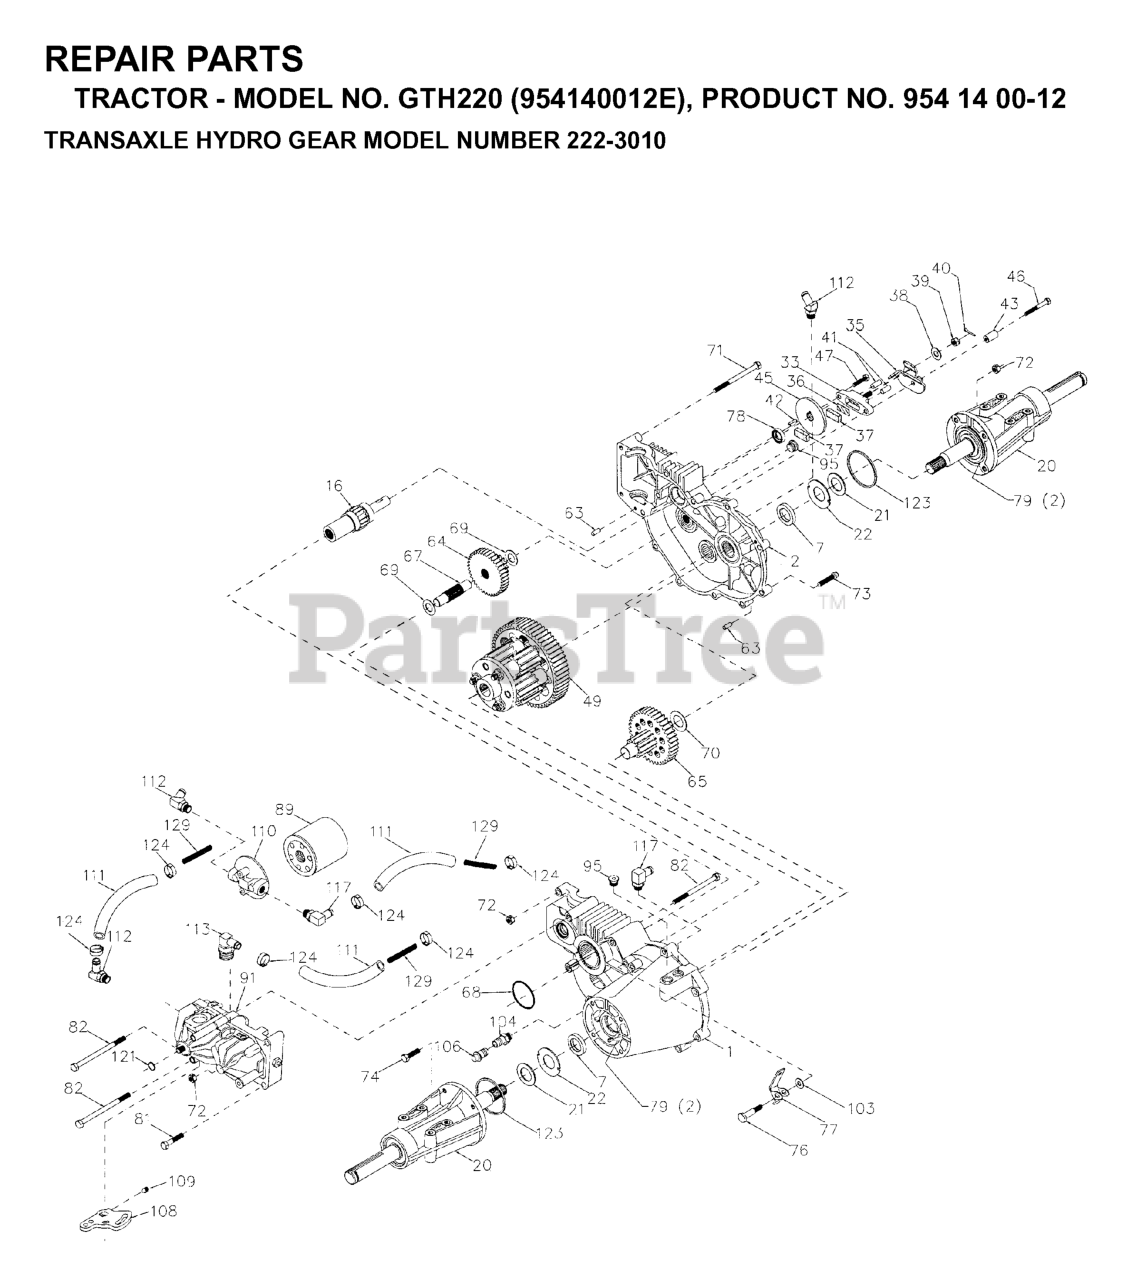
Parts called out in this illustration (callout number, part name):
37	Brake puck
38	Washer 7/8 O.D. x 7/16 x .060
104	Cap, Vent Assembly
106	Fitting, O-Ring Assembly
109	Set Screw
